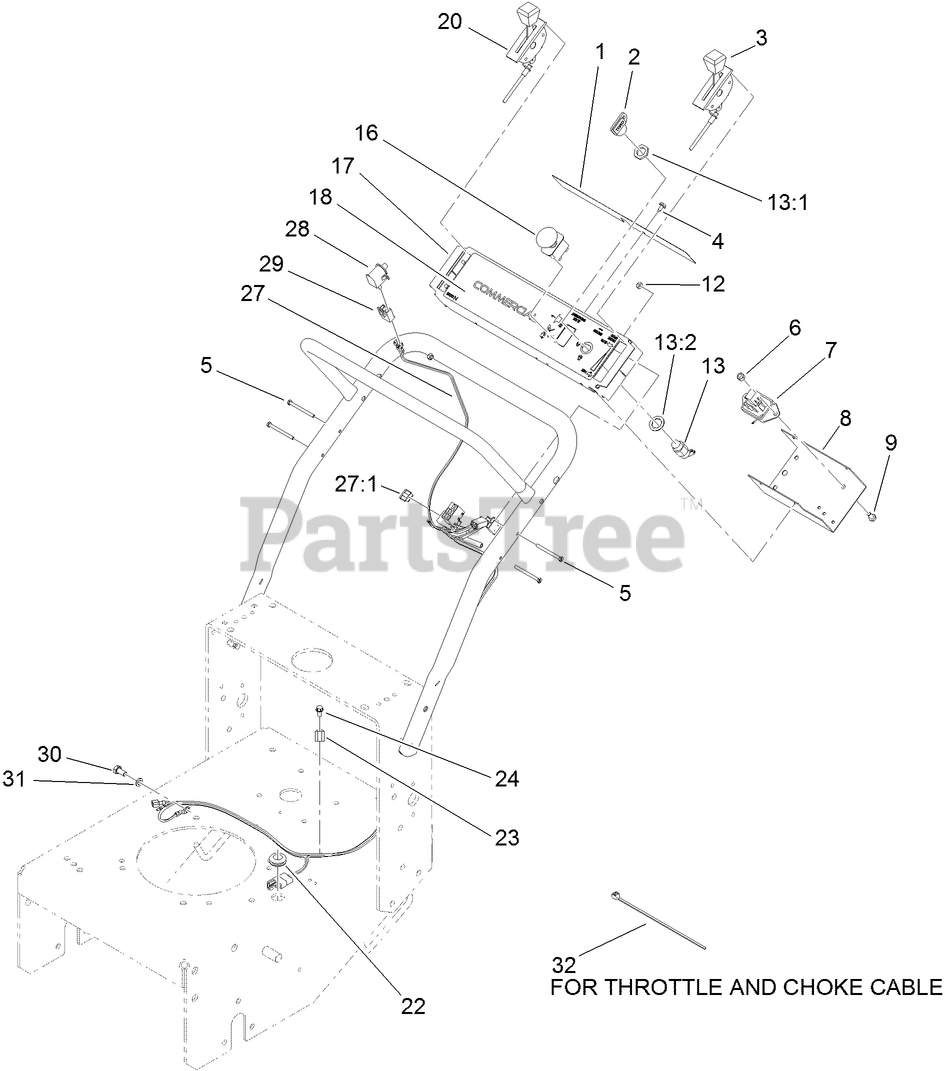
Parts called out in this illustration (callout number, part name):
1	DECAL-DANGER
2	KEY-IGNITION
3	CABLE-THROTTLE
4	SCREW-HWHTF
5	SCREW-SHH
6	NUT-LOCK, NI
7	MODULE-DELAY
8	PANEL-BOTTOM
9	SCREW-HH
12	NUT-LOCK, NI
13	SWITCH-ON / OFF
13:1	NUT-HH
13:2	WASHER-TOOTH, INTERNAL
16	SWITCH-PTO
17	PANEL-CONTROL
18	DECAL-PANEL, CONTROL
20	CABLE-CHOKE
22	GROMMET
23	CLAMP-R
24	SCREW-HWH
27	HARNESS-WIRE
27:1	FUSE-BLADE, 7.5 AMP
28	SWITCH-BAIL
29	CONNECTOR-BODY
30	SCREW-HH
31	WASHER-LOCK
32	TIE-CABLE
